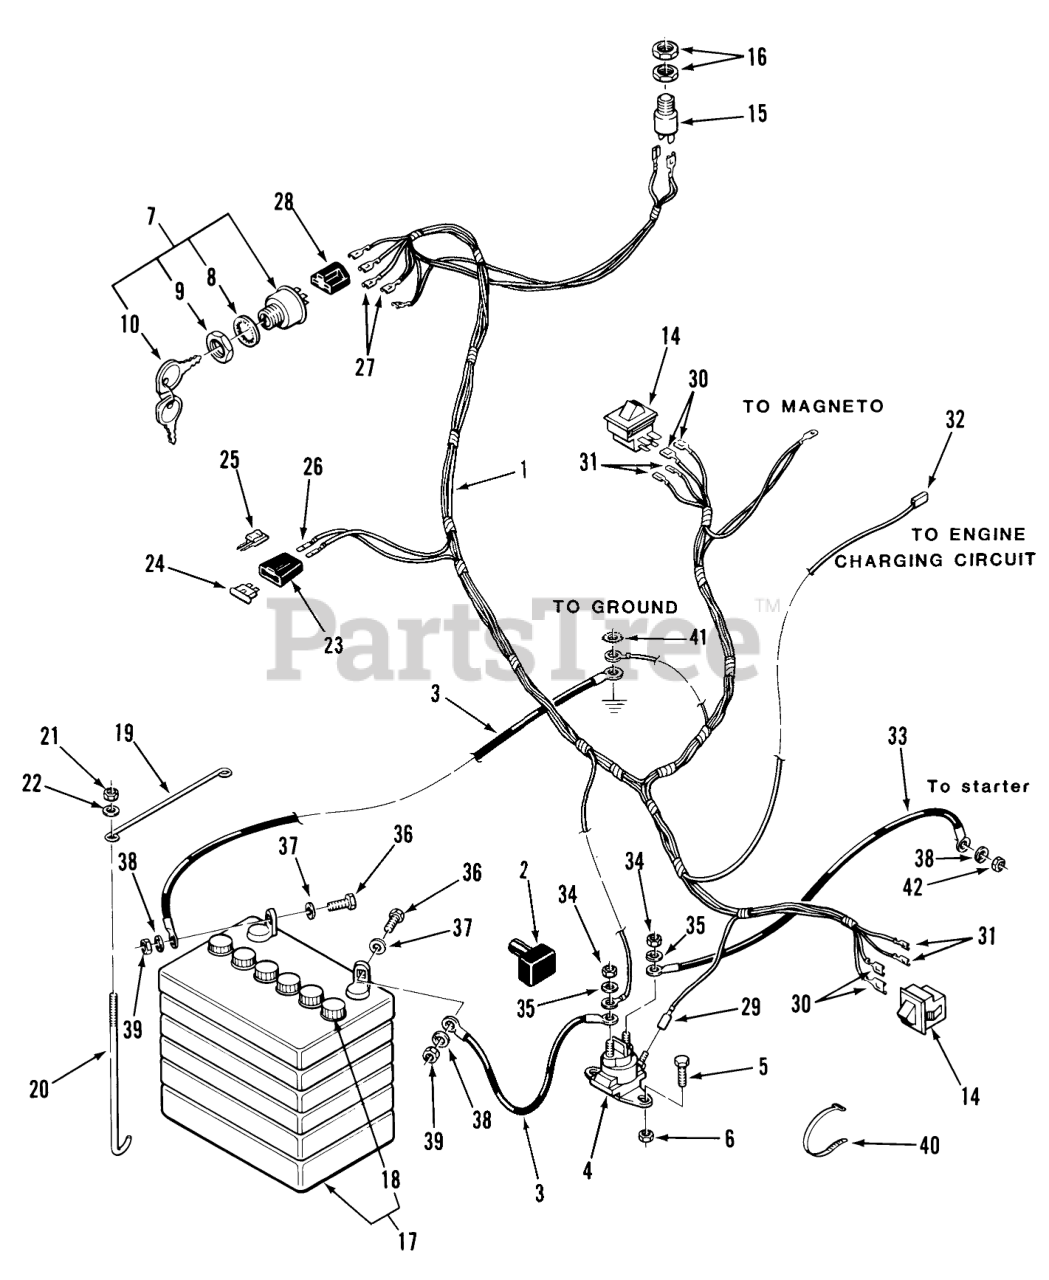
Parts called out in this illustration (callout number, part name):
1	HARNESS WIRING
2	Boot
3	Wire
4	Solenoid
5	Bolt
6	Nut
7	ASSY-SWITCH IGNITION
8	LOCKWASHER
10	Key-EL
14	PTO Interlock Switch
15	SWITCH-SEAT
16	NUT-HEX
17	Battery
19	Lockwasher
20	HOOK-BATTERY RETAINR
21	Nut
23	AUTO-FUSEBLOCK TERM
24	FUSE-BLADE, 15 AMP
26	TERMINAL-FUSE
27	Terminal
28	CONNECTOR-5 WAY-SERV
29	Terminal Part of 5
30	Terminal
31	Wire Terminal (Part of 1)
32	Terminal
33	Wire
34	Nut
35	Washer
36	Bolt
38	Washer
39	Nut
40	PLASTIC TIE
41	LOCKWASHER
42	Nut
